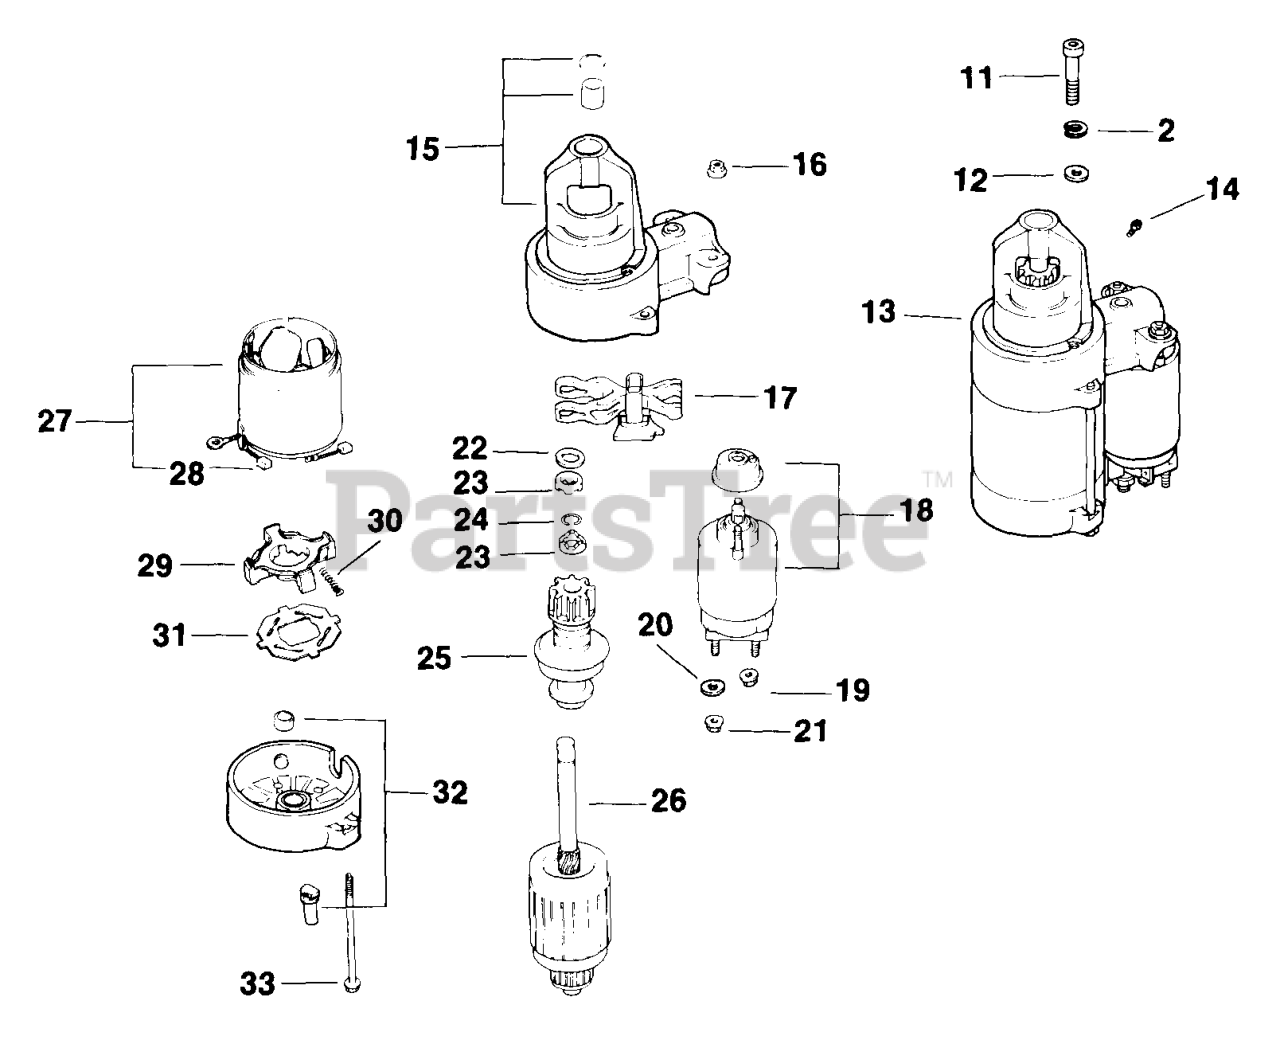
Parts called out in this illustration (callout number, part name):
2	WASHER, SPRING LOCK 1/4"
11	SCREW - (#DSC)
12	WASHER, FLAT 1/4" (O.D. 1/2")
13	ELEC STARTER-SOLENOID SHIFT-(#DSC)
14	SCREW, WSH HD TAP 1/4-20X7/16" USE 25 086 106-S
15	CAP, DRIVE END - DISCONTINUED
17	DRIVE LEVER
20	WASHER - DISCONTINUED
21	NUT - DISCONTINUED
22	KIT - USE 24 755 84
23	KIT - USE 24 755 84
24	KIT - USE 24 755 84
25	DRIVE - (#DSC)
26	ARMATURE-DISCONTINUED
28	BRUSH & SPRING KIT
29	BRUSH HOLDER
30	SPRING, BRUSH
31	INSULATOR
32	CAP, COMMUTATOR END
33	THRU BOLT
